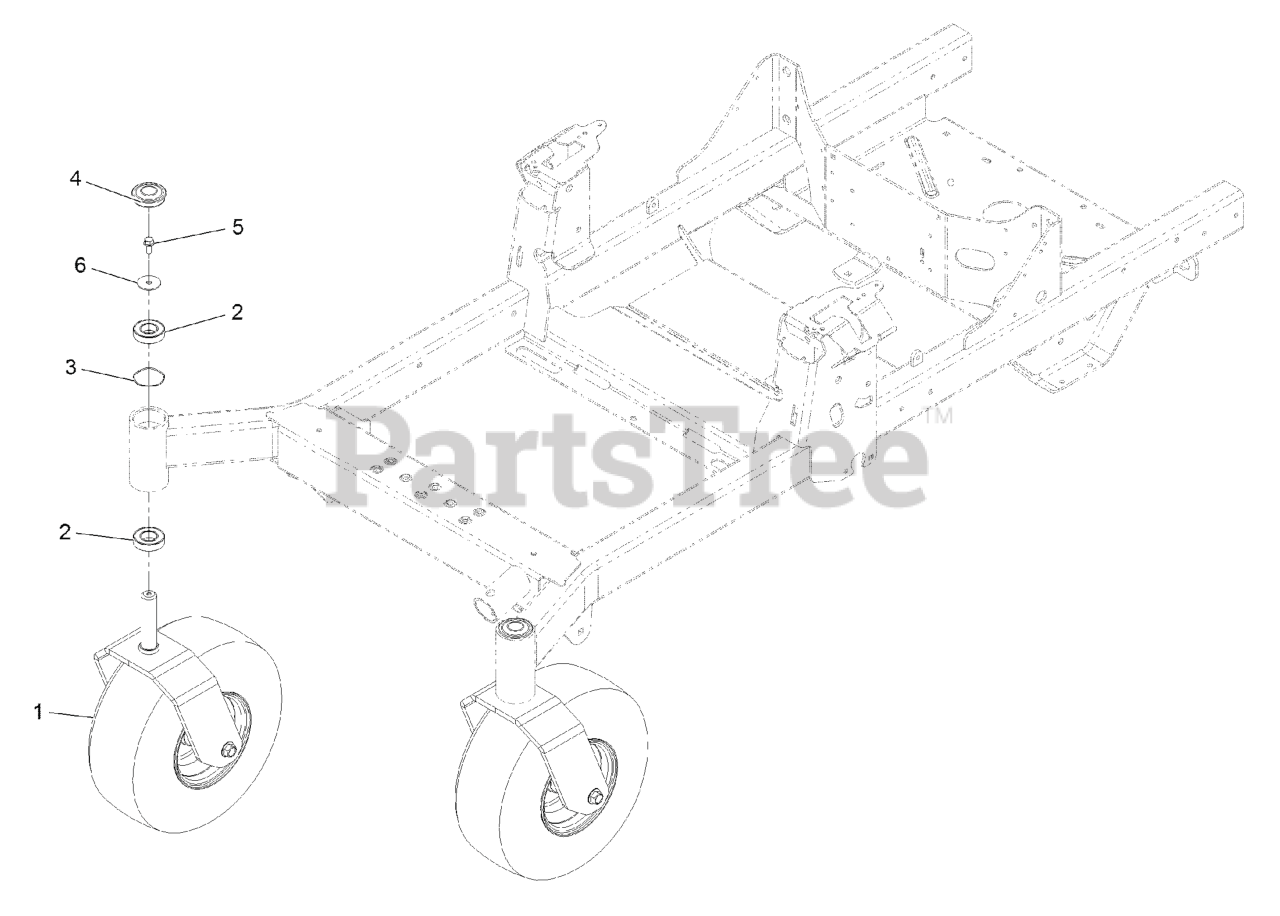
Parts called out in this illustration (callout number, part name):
1	ASM-Front Caster W/Fork
2	BEARING-BALL
4	CAP-GREASE
5	SCREW-HHF
6	WASHER-FLAT
